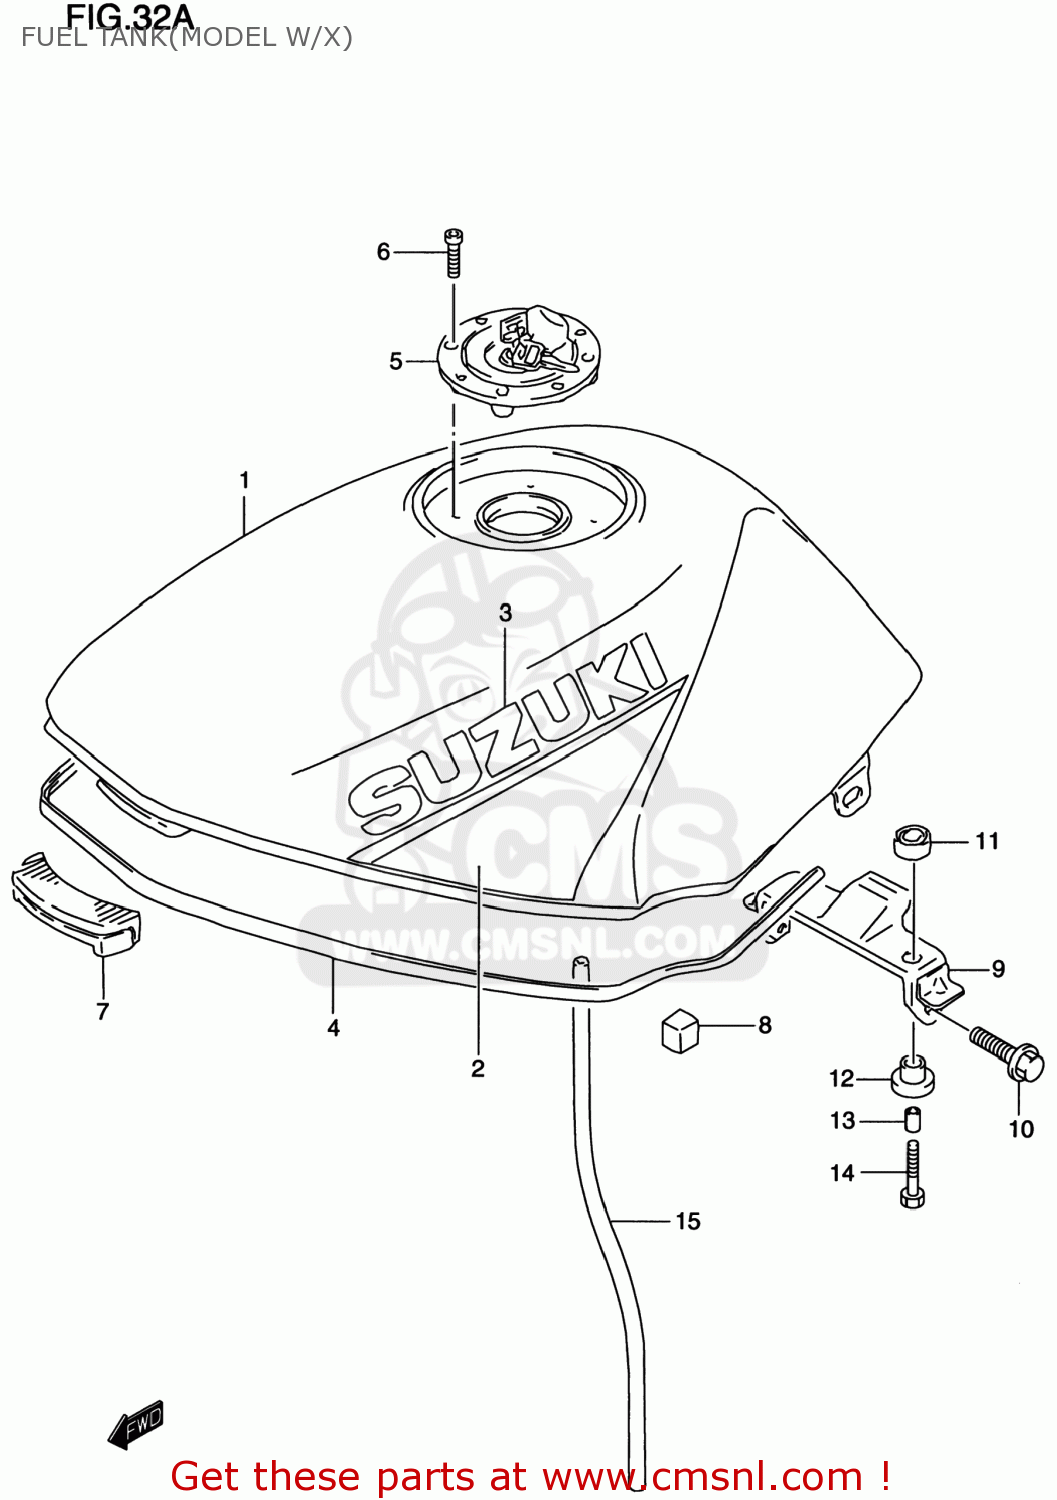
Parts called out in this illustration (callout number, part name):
1	TANK ASSEMBLY,FUEL
2	TAPE SET,FUEL TANK
3	EMBLEM,FUEL TANK
4	MOLDING
5	CAP SET,FUEL
6	BOLT(5X20)
7	CUSHION,FUEL TANK FR
8	CUSHION,FUEL TANK SIDE
9	BRACKET COMP,FUEL TANK
10	BOLT
11	CUSHION
12	CUSHION
13	SPACER(6.5X9X18)
14	BOLT(6X30)
15	HOSE,WATER DRAIN
